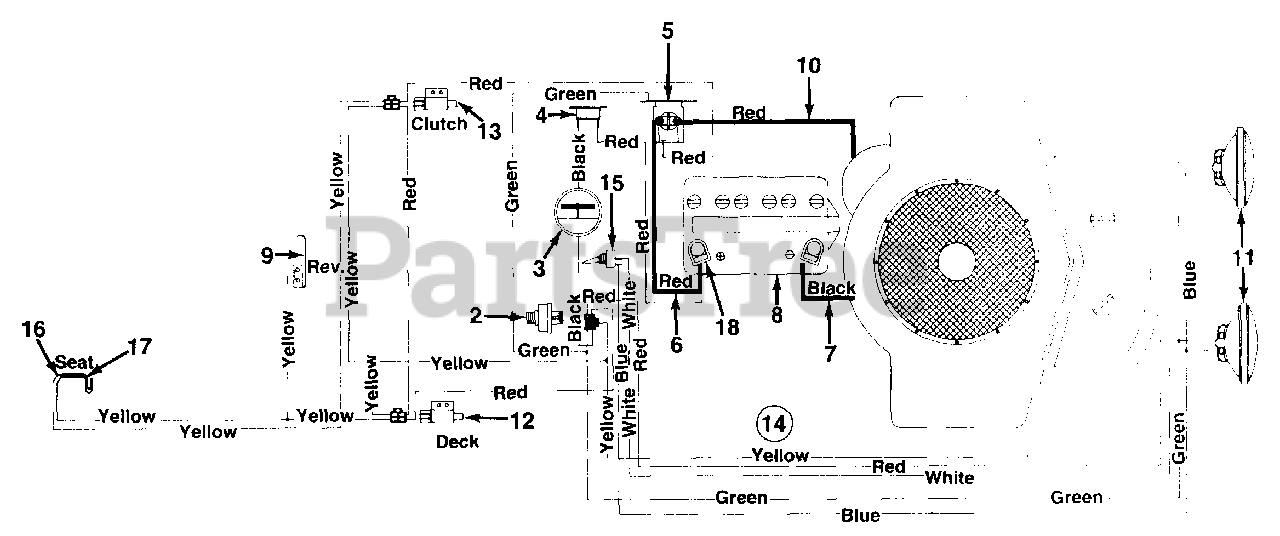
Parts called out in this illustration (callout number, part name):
2	Ignition Switch
3	Ammeter
4	Circuit Breaker
5	Solenoid
6	Electric Wire
7	Electric Wire
8	Battery
9	Spring Switch (Reverse Safety)
10	Electric Wire
11	Headlights
12	Safety Switch (PTO)
13	Safety Switch (Clutch)
14	Wire Harness
15	Light Switch
16	Safety Switch (Seat)
17	Safety Switch (Seat)
18	Battery Boot
